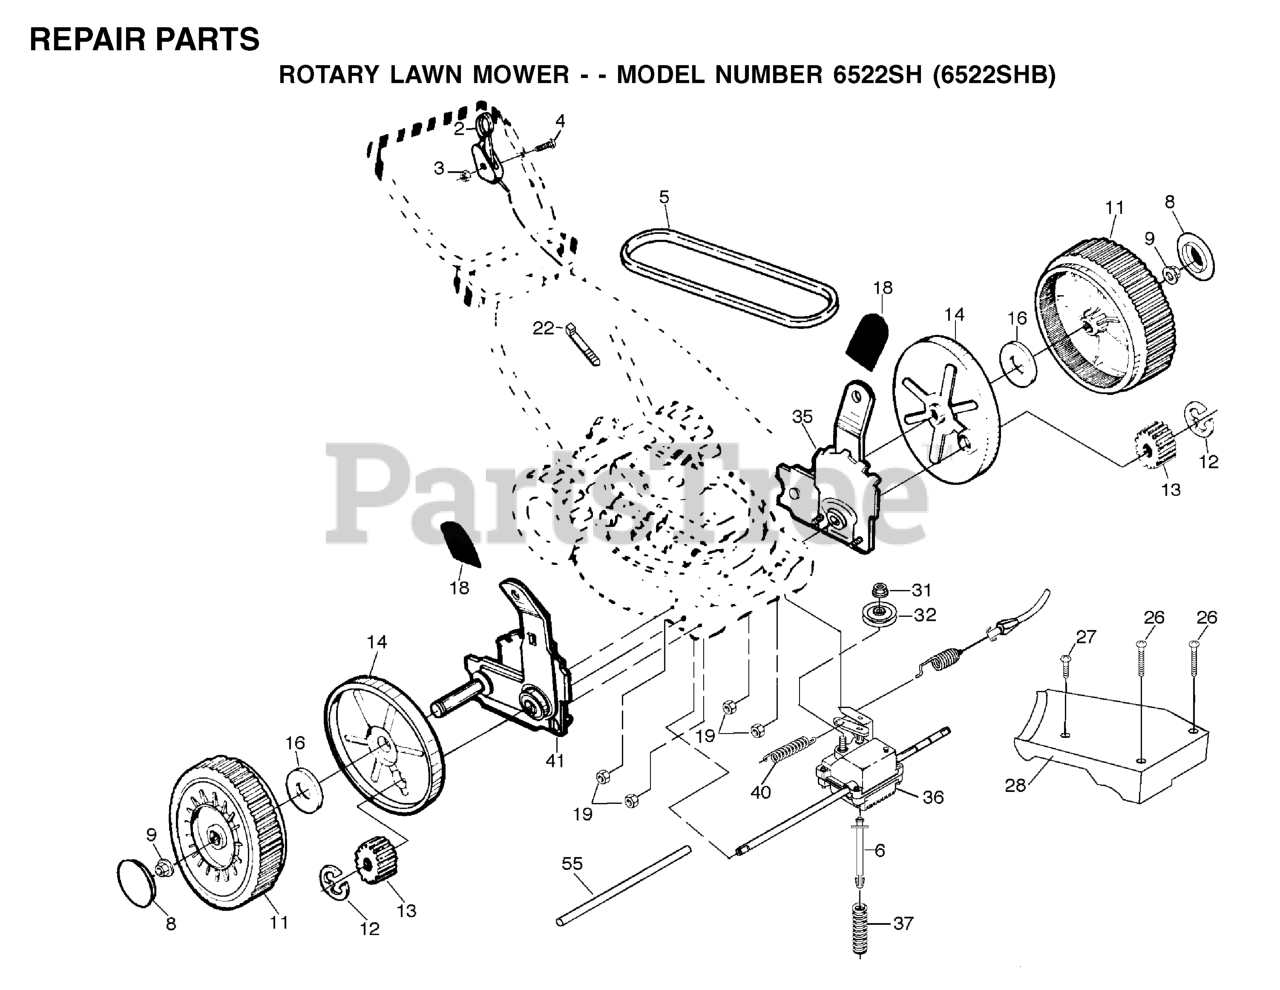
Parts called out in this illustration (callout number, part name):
2	CONTROL
3	LOCK NUT
4	SCREW.PAN.HEAD
5	BELT THERM .32
6	SPRING RETAINER
8	CAP.HUB.BLACK.WALK
9	NUT
11	WHEEL.8X2.PR.LP.RADII.GY
12	E-RING 7/16 RE
13	PINION GEAR
14	DUST SHROUD PM
16	WASHER FLUT
19	NUT
22	TIE GUIDE
27	TAPPING SCREW
28	COVER DRIVE
31	FLANGED LOCKNUT 3/8-16 ZINC
32	PULLEY
35	WHEEL ADJ ASM (L)
36	GEAR CASE ASMBLY
37	SPRING.EXTENSION
41	KIT.ADJUSTER.ASM.(151514).RT
55	DRV SHAFT TUBE PM
